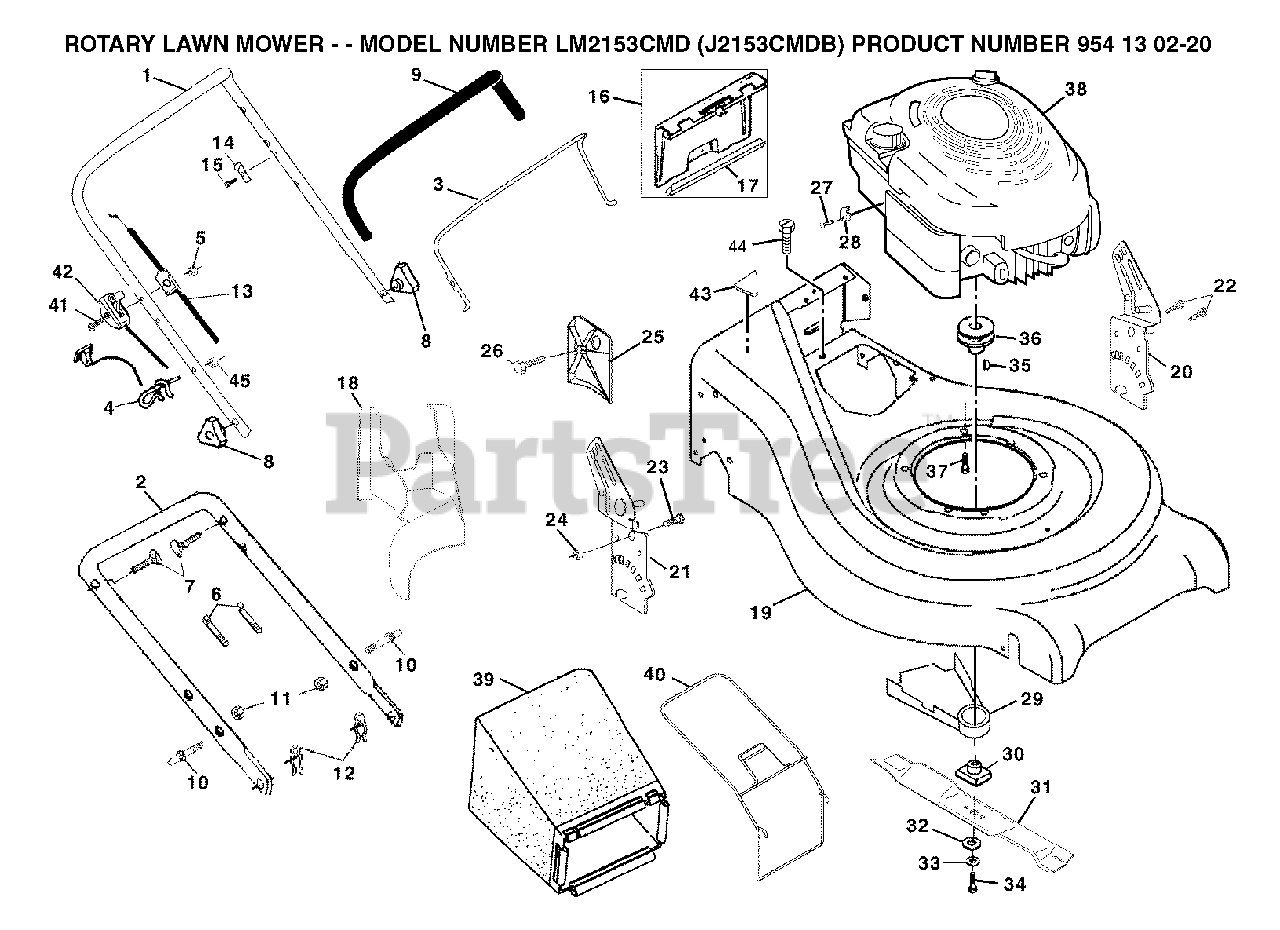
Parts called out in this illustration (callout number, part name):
2	HANDLE
4	ROPE, GUIDE
5	NUT
6	TIE GUIDE
7	HANDLE BOLT
9	GRIP.HANDLE.FOAM
10	BOLT
11	NUT
12	HAIRPIN COTTER
13	ENGINE ZONE CONTROL
14	BRACKET UPSTOP
16	REAR DOOR KIT
17	SEAL DOOR 21
18	MULCHER PLUG
20	.RACKET
22	SELF-TAPPING SCREW 5/16-18X3/4
23	BOLT, HEX HEAD 5/16-18
24	NUT.71038.31-18.HEX.NYLOCK
25	CLIPPING DEFLECTOR
28	CABLE CLAMP(ENGINE)
29	SHIELD.DEBRIS.21.RWGD.EZ
30	BLADE ADAPTER
32	WASHER,HARDEN
33	LOCKWASHER
34	SCREW, HEX HD 3/8-24 X 1-3/8
35	PULLEY.ENG.25MMM
36	HI-PRO KEY
37	BOLT 3/8-16X1-1/8
39	GBAG.300N2.BLACK.GENERIC
40	FRAME.GRASS.CATCHER.21.RGD
42	CONTRL.THROTTLE.
43	DECAL.INTERNATIONL.CUTFINGER
45	NUT
